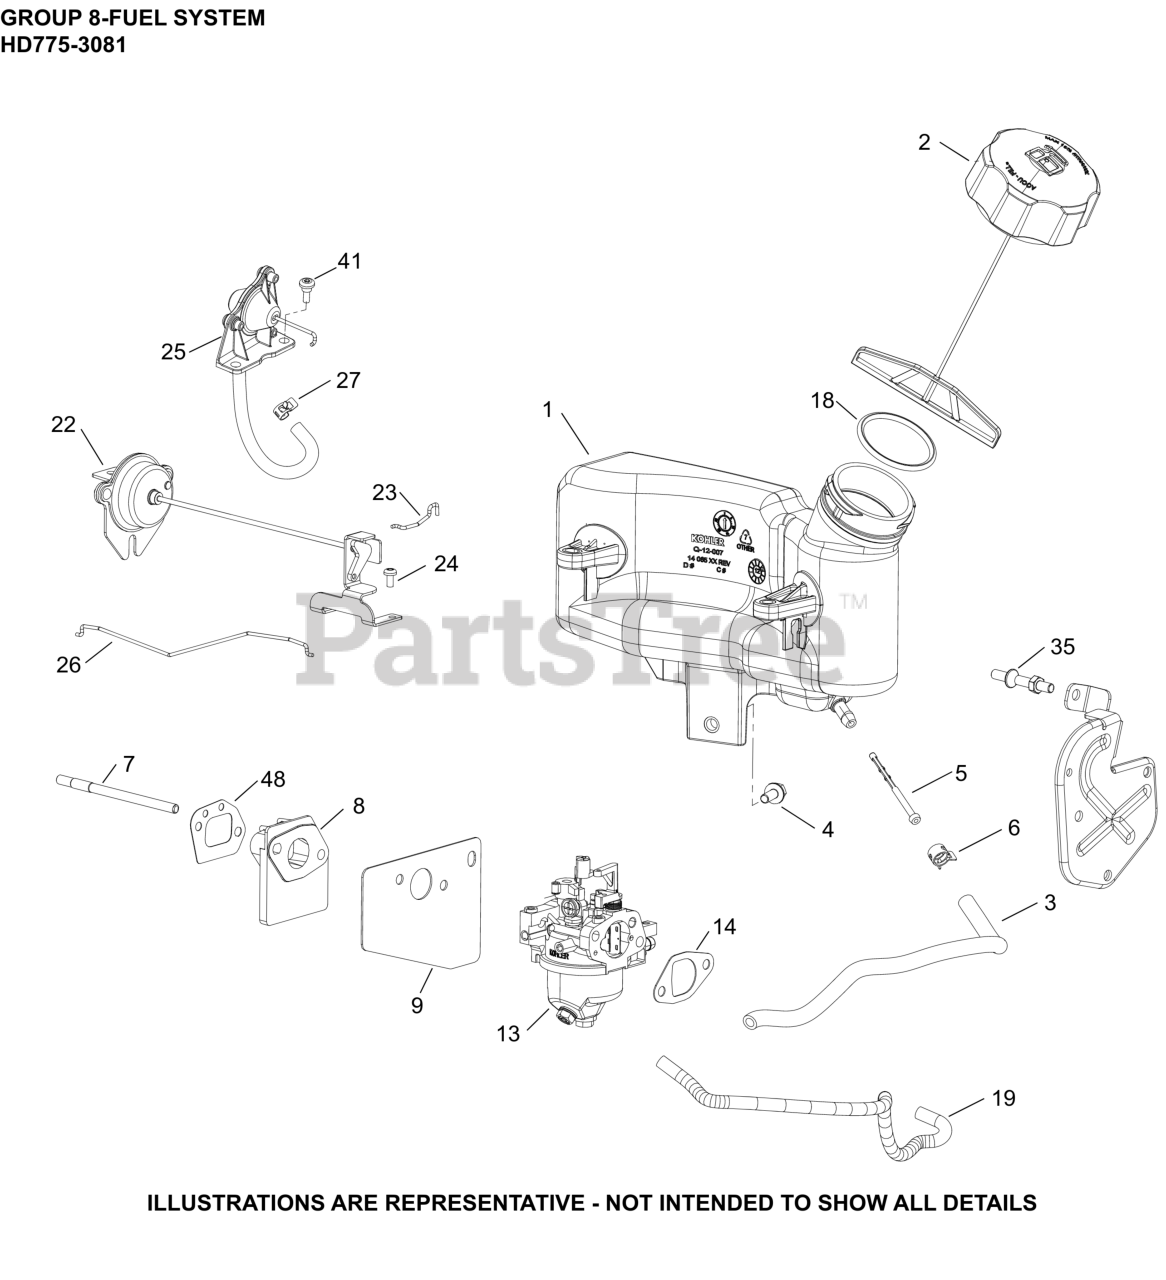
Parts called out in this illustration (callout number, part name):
1	TANK, FUEL 1.4L FOR EUROPE ONLY
2	CAP ASSEMBLY, FUEL
3	HOSE, FUEL LOW-PERMEATION
4	SCREW, HEX FLANGE (M6)
5	FILTER, FUEL IN-NIPPLE
6	CLAMP, HOSE (NON-CALIF)(#1423710S)
7	STUD,M6X1.0X100.2MM
8	KIT, SPACER
9	KIT, CARBURETOR HEAT SHIELD GASKET
13	KIT, CARBURETOR 13 MM AUTO CHOKE
14	KIT, INTAKE GASKET
18	SEAL, FUEL CAP- (#DSC)
19	HOSE, EVAPORATIVE
22	ARM ASSY,AUTO CHOKE-USE 14 187 18-S
23	LINKAGE, AUTO CHOKE
24	SCREW, M4 THRD FRMNG-(#25086439S)
25	DIAPHRAGM, ASSEMBLY
26	LINKAGE, CHOKE
27	CLAMP, HOSE
41	SCREW, SHOULDER-(#25086440S)
48	GASKET SPACER
NI	KIT,HIGH AL(4000-8000 FT)USE 14 755 04-S
NI	KIT, CARBURETOR REPAIR (RUIXING)
